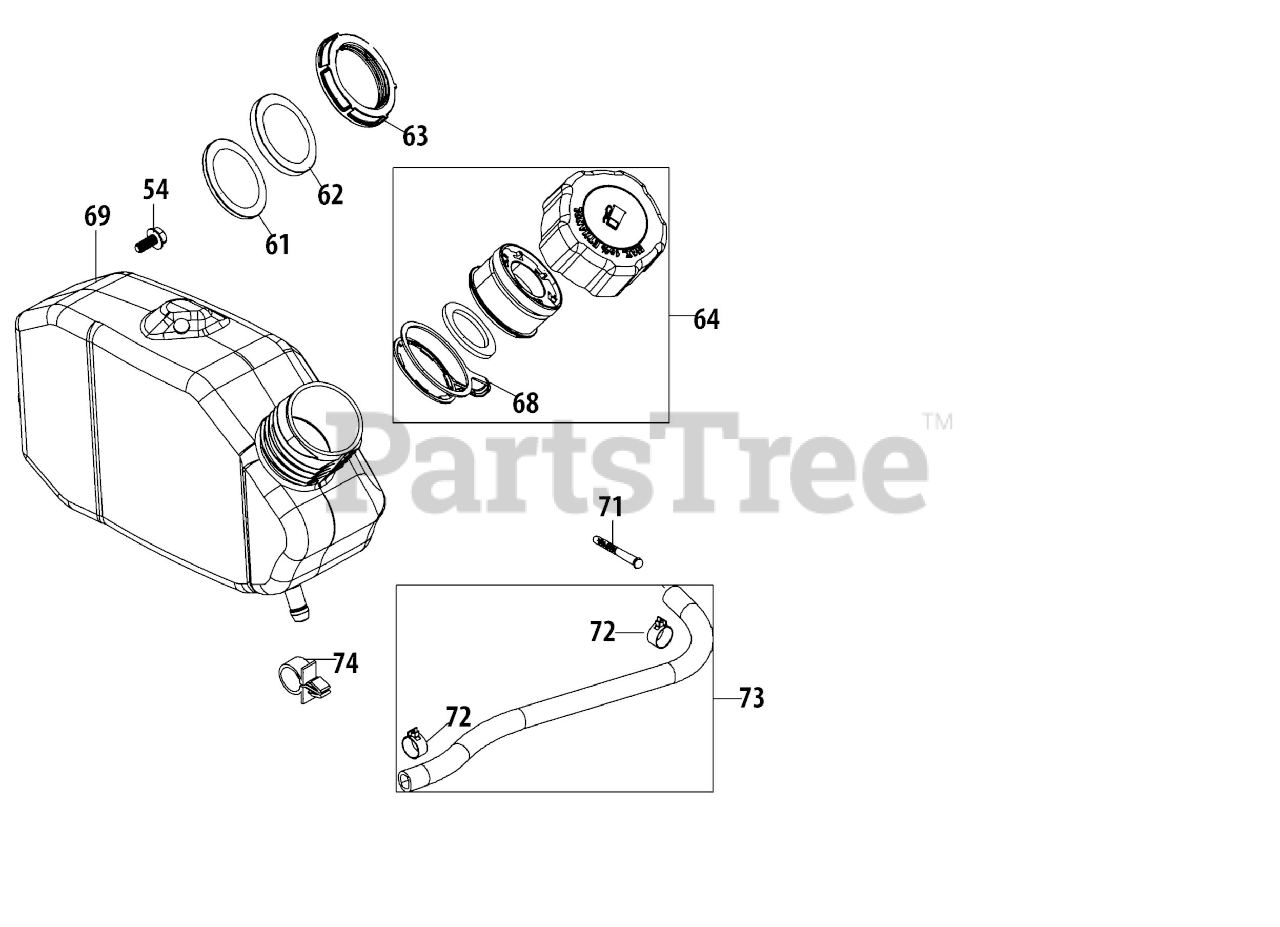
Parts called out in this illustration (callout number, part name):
54	Bolt M6X14 Multi-Purpose
61	Fuel Tank Lower Grommet
62	Fuel Tank Upper Grommet
63	Fuel Tank Nut
64	Fuel Cap Assembly
68	Fuel Cap Tether
71	Fuel Filter
72	Fuel Hose Clamp
73	Fuel Hose
74	Plastic Support Clamp
